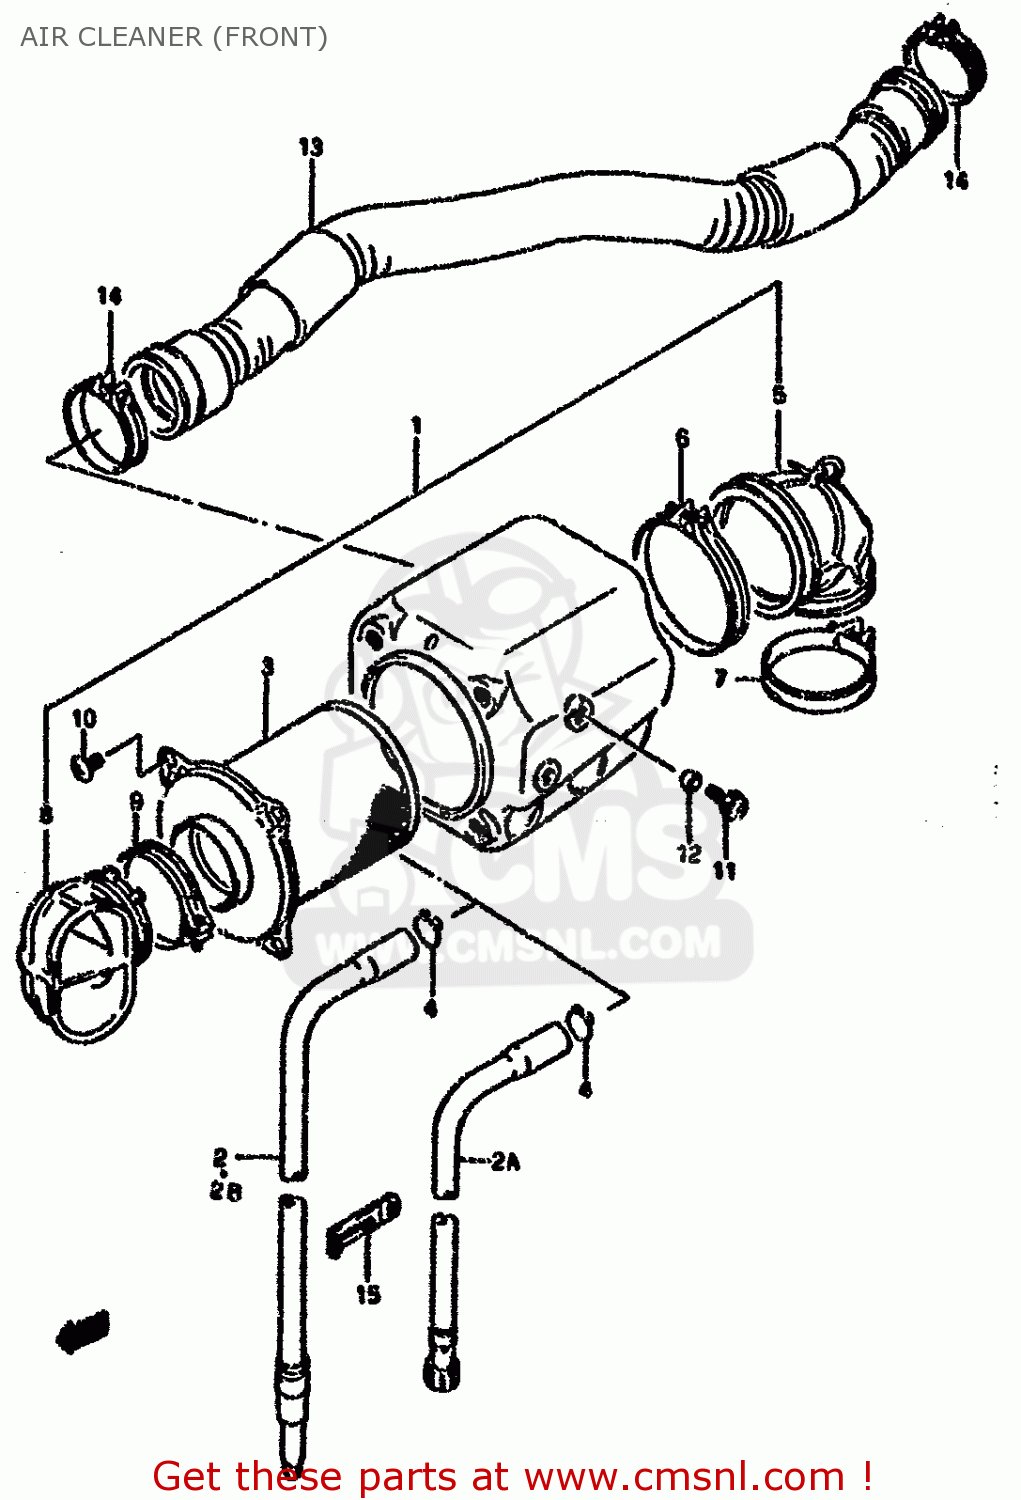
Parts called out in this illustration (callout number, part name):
1	CLEANER ASSY,AIR FRONT
2	TUBE,DRAIN
2A	TUBE,DRAIN
2B	TUBE,DRAIN
3	FILTER ASSY,AIR
4	CLIP
5	TUBE,AIR CLEANER OUTLET
6	CLAMP
7	CLAMP
8	TUBE,INLET
9	CLAMP
10	SCREW
11	SCREW
12	SPACER(6.2X8.3X6.1)
13	HOSE,AIR CLEANER
14	CLAMP
15	CLAMP
